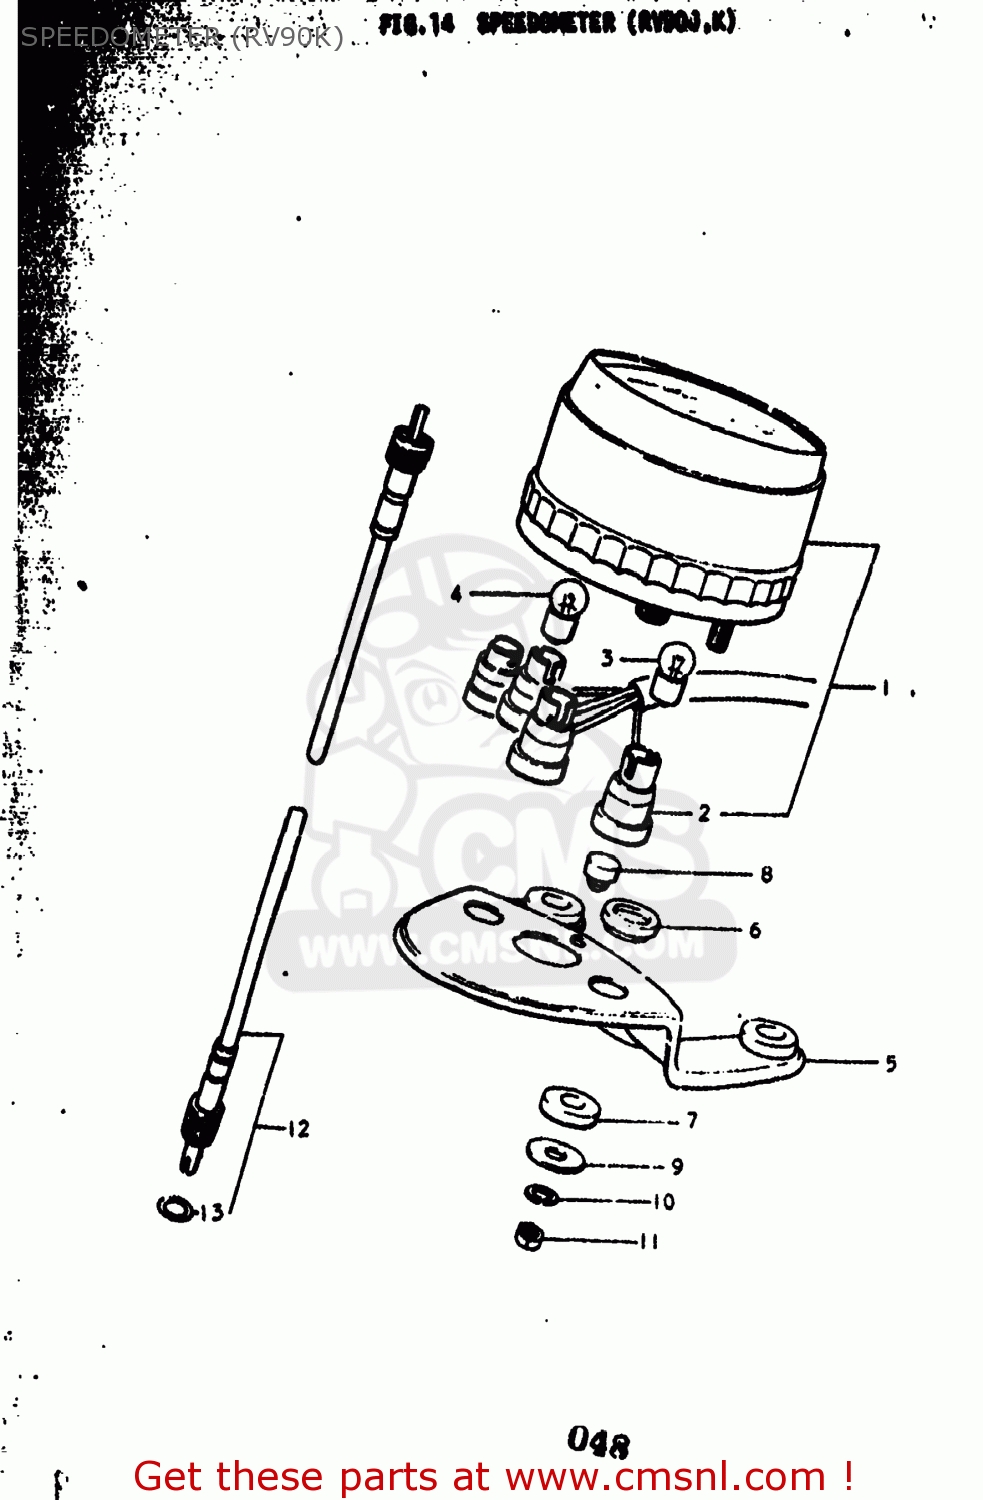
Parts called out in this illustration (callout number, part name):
1	SPEEDOMETER ASSEMBLY
2	SOCKET,METER
3	BULB(6V/3W)
4	BULB(6V1.7W,STANLEY,A61A)
5	BRACKET,METER
6	CUSHION,METER
7	CUSHION
8	CUSHION,METER
9	WASHER(5.5X16X1.5)
10	LOCK WASHER
11	NUT
12	CABLE ASSY,SPEEDOMETER
13	SEAL,OIL METER CABLE
